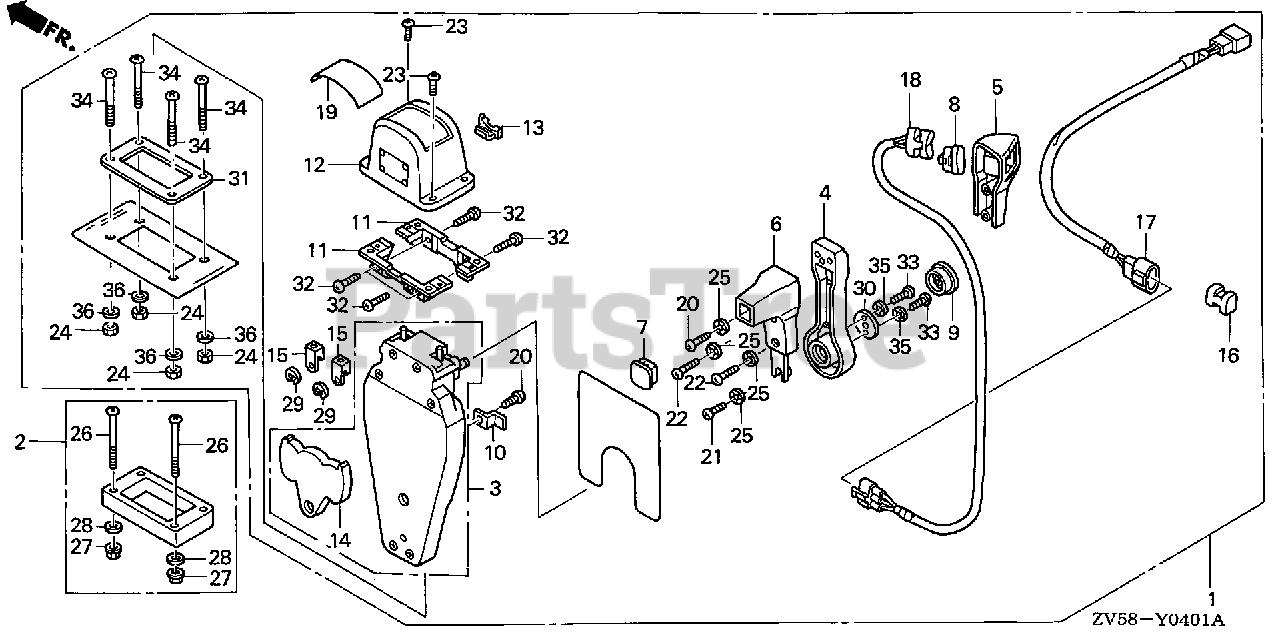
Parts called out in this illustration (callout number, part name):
1	BOX KIT, L. REMOTE CONTROL (TOP MOUNT SINGLE)
2	SPACER KIT, REMOTE CONTROL BOX (TOP MOUNT SINGLE)
3	HOUSING ASSY., R. (INNER) (TOP MOUNT)
4	HANDLE, REMOTE CONTROL
5	COVER, R. GRIP
6	GRIP, REMOTE CONTROL HANDLE
7	CAP, GRIP
8	CAP, SWITCH
9	BUTTON, THROTTLE
10	PLATE, CABLE CLAMP
11	BRACKET, REMOTE CONTROL HOUSING
12	HOUSING, REMOTE CONTROL BOX
13	HOUSING, LEAD
14	PLATE, DWELL
15	TERMINAL, CABLE
16	SPACER, CABLE CLAMP
17	SUB-HARNESS ASSY., POWER TRIM-TILT (B)
18	SWITCH ASSY., POWER TRIM-TILT
19	MARK, REMOTE CONTROL (SINGLE)
20	SCREW, PAN (5X16)
21	SCREW, PAN (5X10)
22	SCREW, PAN (5X20)
23	SCREW, PAN (4X10)
24	NUT, HEX. (5MM)
25	WASHER, LOCK (5MM)
26	SCREW, PAN (5X65)
27	NUT, FLANGE (5MM)
28	WASHER, PLAIN (5MM)
29	E-RING (6MM)
30	PLATE, HANDLE
31	GASKET, SINGLE
32	SCREW, PAN (5X18)
33	SCREW, PAN (6X18)
34	SCREW, PAN (5X40)
35	WASHER, LOCK (6MM)
36	WASHER, PLAIN (5MM)
